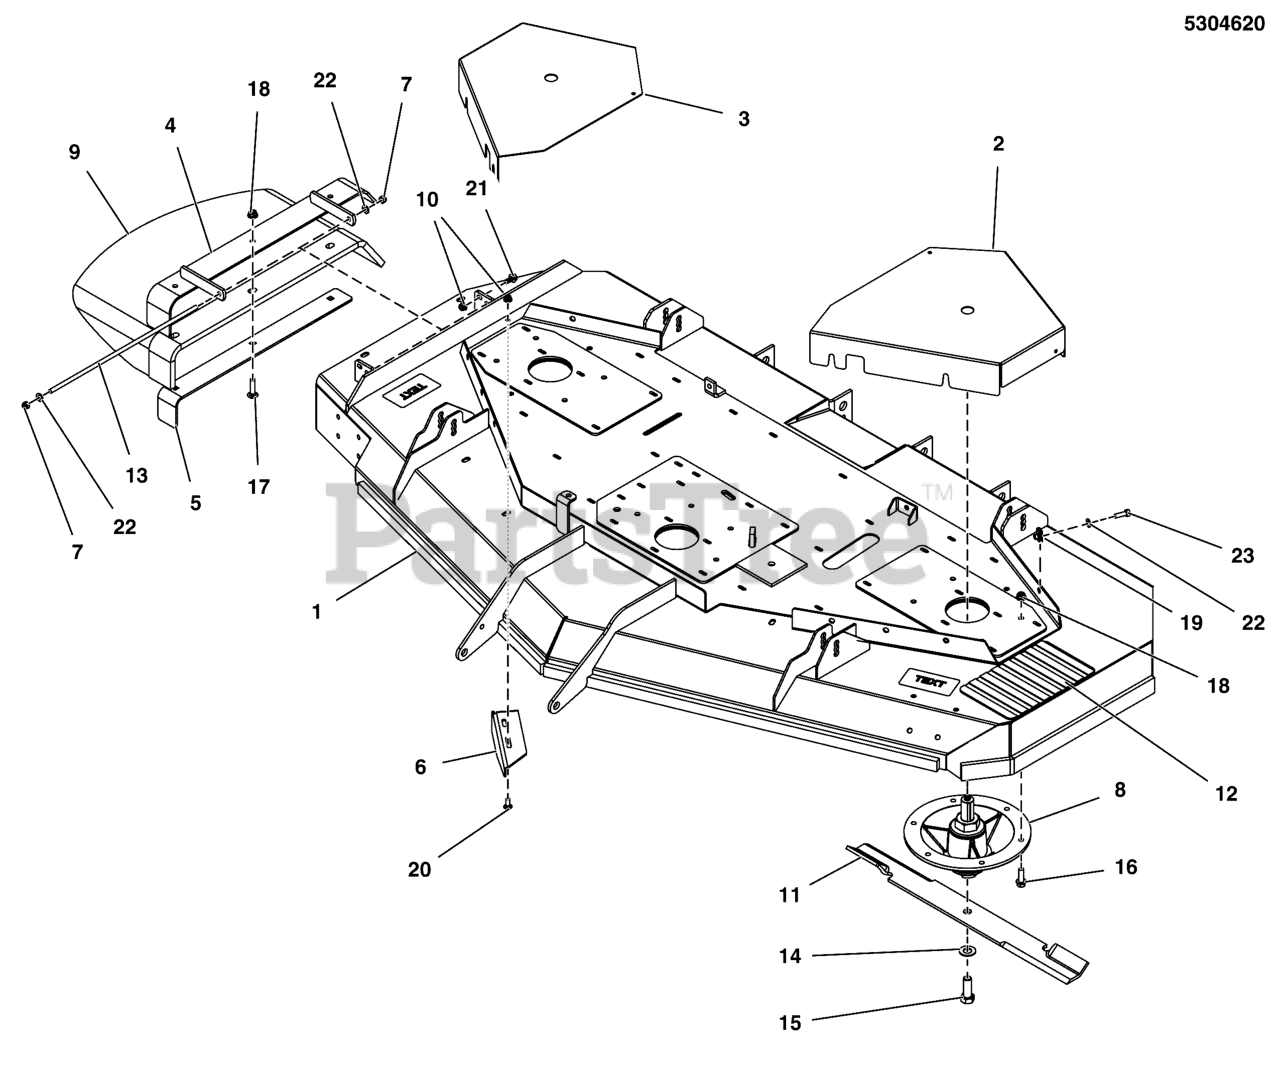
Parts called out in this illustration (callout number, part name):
1	DECK SHELL W/DECALS, 72, 3200Z (5415350B)
1	DECK SHELL W/DECALS, 72-3200E (5415350B)
1	DECK SHELL W/DECALS, 3200-72 (5417007B)
1	DECK SHELL W/DECALS, 3200-72E (5417007B)
2	GUARD,MOWER DECK,LH,72 2-BELT 3200 - RED
3	GUARD,MOWER DECK,RH,72 2-BELT 3200 - RED
5	SUPPORT, DISCHARGE CHUTE - BLK
6	PLATE, DEFLECTOR, 72 - BLK
7	NUT, 5/16-24 HEX NYLON LOCK
8	SPINDLE ASSEMBLY
9	CHUTE, RUBBER DISCHARGE (5104442)
10	NUT, 5/16-18 HEX NYLOCK FLANGE NUT
11	BLADE, 25 X 25 X 2.50, HIGH LIFT (SET OF 3)
12	SAFETY WALK, 9.75 X 6.00
13	ROD, MOUNT, CHUTE, 61, CZ
14	WASHER, BLADE BOLT, 9/16" F436, CZ
15	BOLT, 5/8-11 X 1-3/4 GD8
16	BOLT, 3/8-16 X 1-1/4, FLANGE, GD 5, CZ
17	BOLT, 3/8-16 X 1-1/2, CARRIAGE, GD5, CZ
18	NUT, 3/8 - 16 HEX NYLOCK FLANGE
19	BODY CLIP, 5/16-18-7GA MATERIAL
20	BOLT, 5/16-18 X 3/4, CARRIAGE, GD5, CZ
21	BOLT, 5/16-18 X 3/4 GD5
22	WASHER, 5/16" SAE
23	BOLT, 5/16-18 X 1" GRD5 YZ
